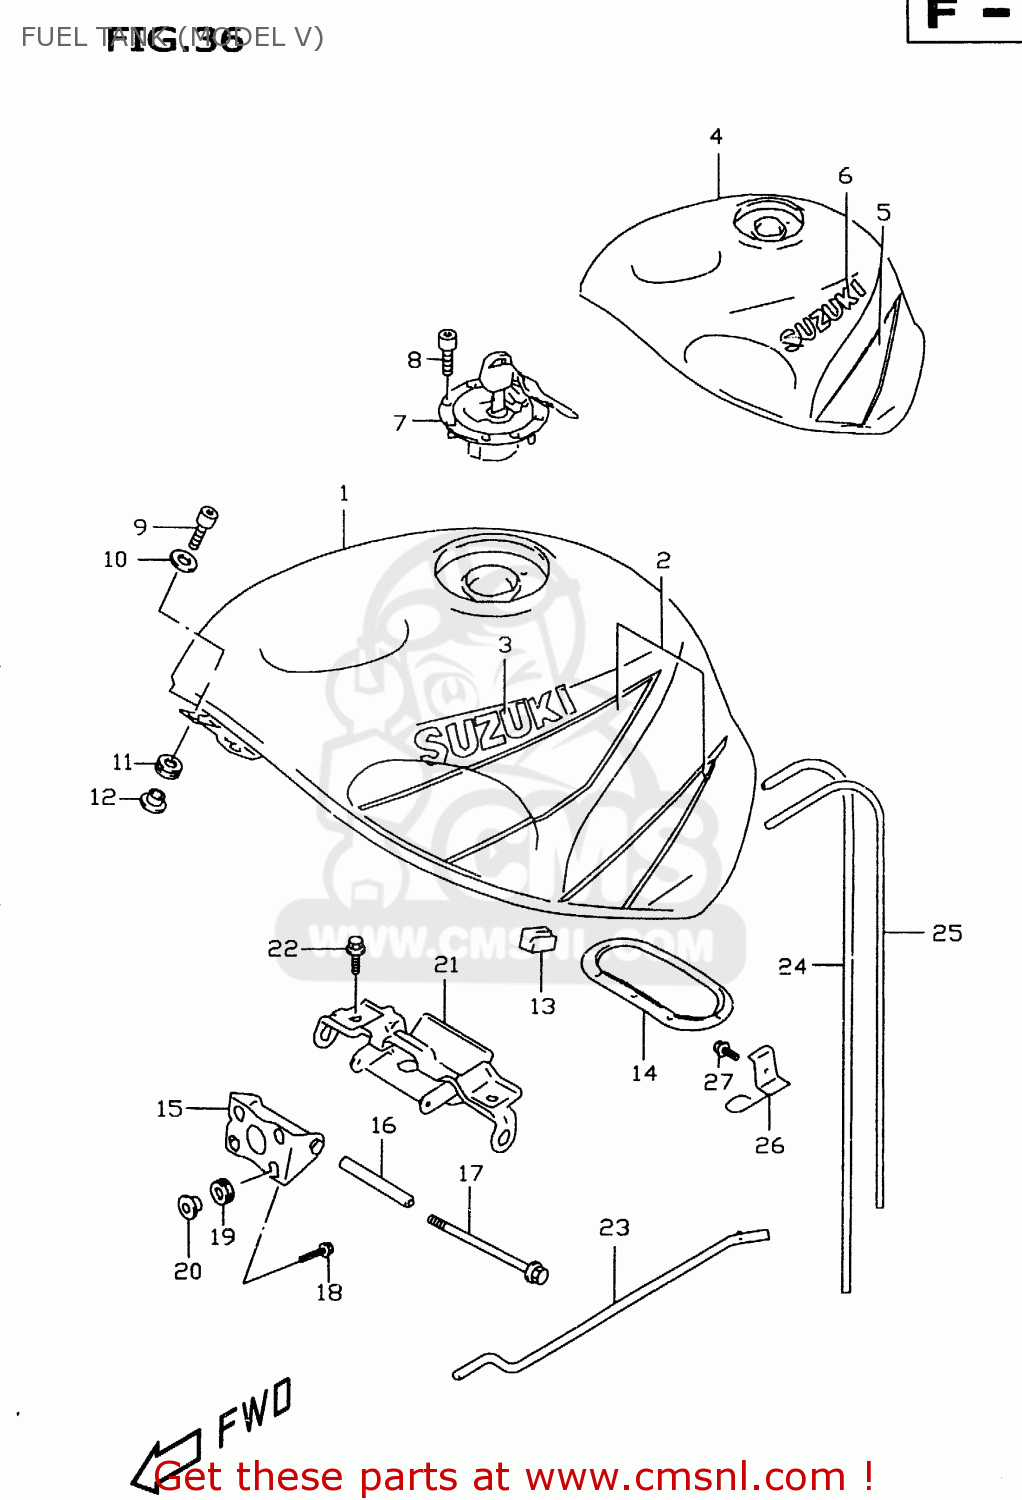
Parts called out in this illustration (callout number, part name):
1	TANK ASSEMBLY,FUEL
2	TAPE SET,FUEL TANK
3	EMBLEM,FUEL TANK
4	TANK ASSEMBLY,FUEL
5	TAPE SET,FUEL TANK
6	EMBLEM,FUEL TANK
7	CAP SET,FUEL TANK
8	BOLT(5X20)
9	SCREW(6X25)
10	WASHER
11	CUSHION
12	WASHER
13	CUSHION,FUEL TANK SIDE
14	PACKING,FUEL PUMP
15	BRACKET COMP,FUEL TANK
16	SPACER,FUEL TANK RR
17	BOLT
18	BOLT 6X20,WITH PLAIN WASHER
19	CUSHION
20	WASHER
21	BRACKET,FUEL TANK NO.2
22	BOLT
23	STAY,FUEL TANK
24	HOSE(5X8.2X600)
25	HOSE(7X10.2X600)
26	GUIDE COMP,DRAIN HOSE
27	BOLT
